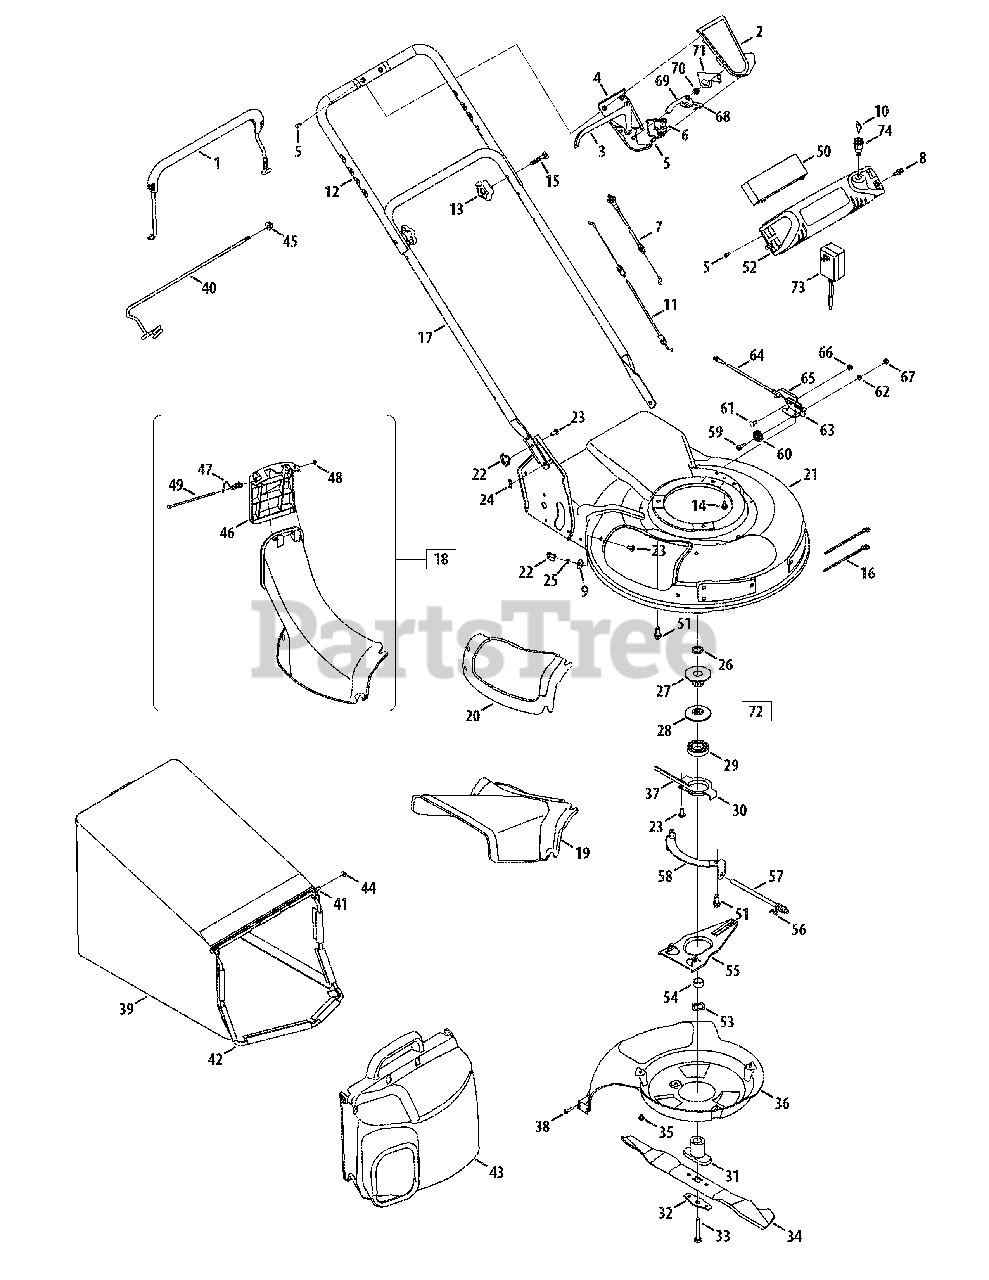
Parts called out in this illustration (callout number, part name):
1	Blade Control
2	Upper Control Housing
3	Drive Control
4	Lower Control Housing
5	C Sunk Tap Screw, #10 x.75 Lg
6	Cable Mounting Cap
7	Drive Cable - 51"
8	Rivet
9	Washer, Flat, .260 x .720 x .060
11	Control Cable - 46"
12	Upper Handle
13	Star Knob
14	Screw, 1/4-20 x .625
15	Carriage Bolt, 5/16-18 x 2.0
16	Cable Tie
18	Adapter Assembly
19	Side Discharge Chute
20	Mulch Cover
22	Wing Nut
23	Carriage Bolt, 1/4-20 x .75"
24	Cotter Pin
25	Push Nut, .25 x ID x .50 OD
26	Sleeve Spacer, .88ID x 1.13OD
27	Half Pulley: 2.62 OD
28	Half Pulley: 2.62 OD x 1.61
29	Ball Bearing
31	Blade Adapter
32	Blade Bell Support
33	Hex Bolt, 3/8-24 x 2.5
34	21" Mulching Blade
35	Screw, 1/4-20 x 3.75
36	Baffle
37	Belt, 3/8 x 39.24
38	Screw, 1/4-15 x .750
39	Grass Catcher
40	Support Rod w/ Rope Guide
41	Pivot Rod
42	Grass Catcher Frame
43	Grass Catcher Cover
44	Cap Nut
45	Flange Lock Nut, 5/16-18
46	Chute Door
47	Torsion Spring
48	Push Cap
49	Pivot Rod
50	12V Battery
51	Sems Screw, 3/8-16 x 1.00
52	Harness Assembly
53	Wave Washer, 1.38 ID x.88 OD
54	Slve Spacer, .88 ID x 1.00 OD
57	Pivot Shaft
59	Shlder Screw, .375 ID x 1/4-14
60	Cable Roller
61	Carriage Screw, 1/4-20 x .62
62	Lock Washer, 1/4
63	Cable Mounting Bracket
64	6 Speed Cable
65	Cable Adjustment Bracket
66	Hex Nut 1/4-20
67	Hex Nut 1/4-28
68	Shift Lever Spring
69	6 Speed Shift Lever
70	Gear Insert
71	6 Spd. Rack Cable Bracket
72	Pulley Assembly
73	12V Battery Charger
74	Key Switch
